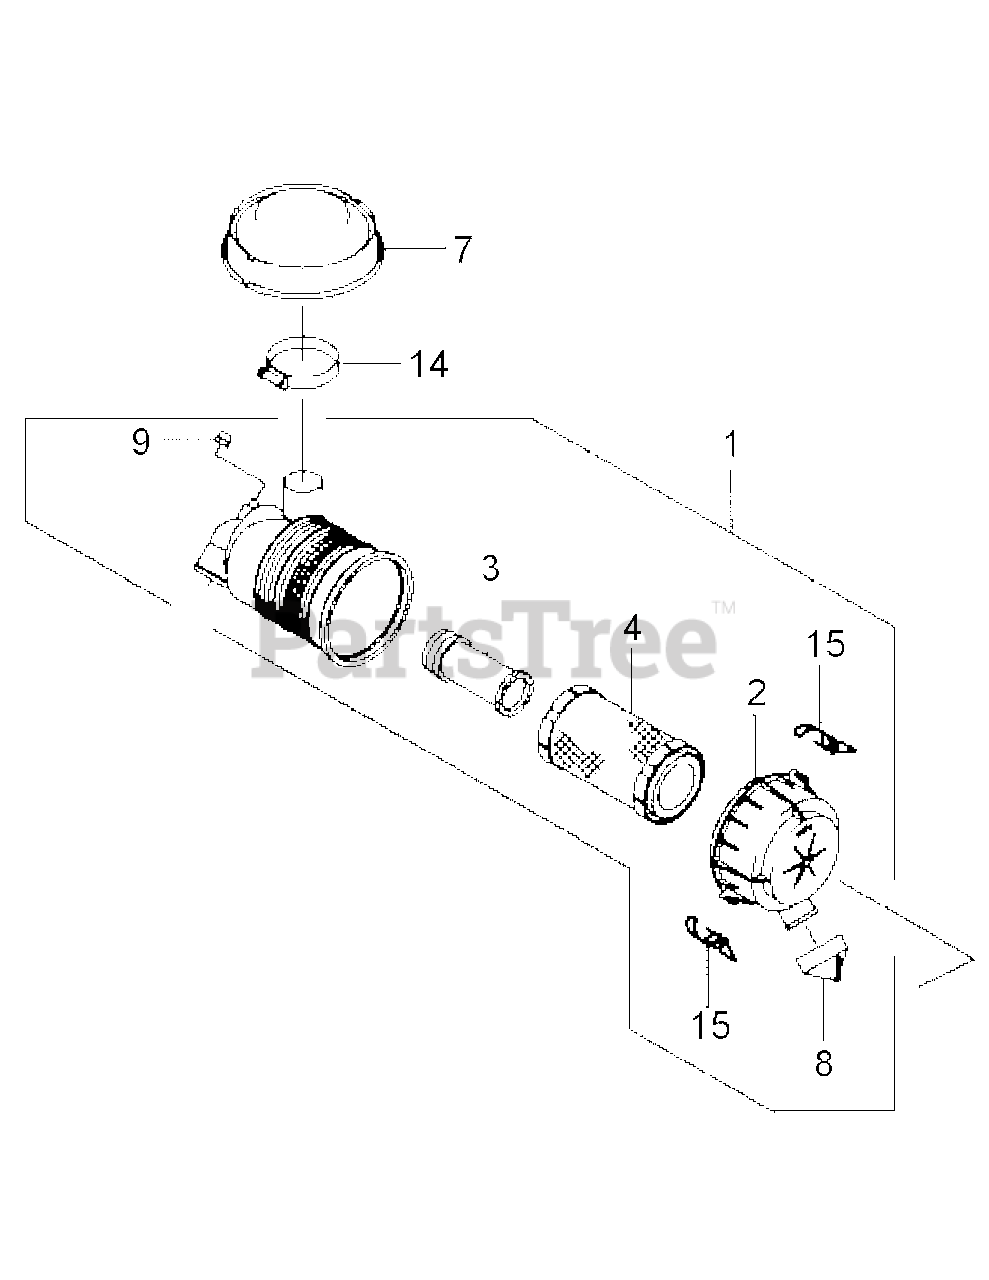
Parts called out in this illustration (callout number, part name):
1	AIR FILTER ASSY.
2	AIR FILTER CASE
3	AIR FILTER ELEMENT
4	PRE FILTER ELEMENT
7	CAP
14	CLAMP
